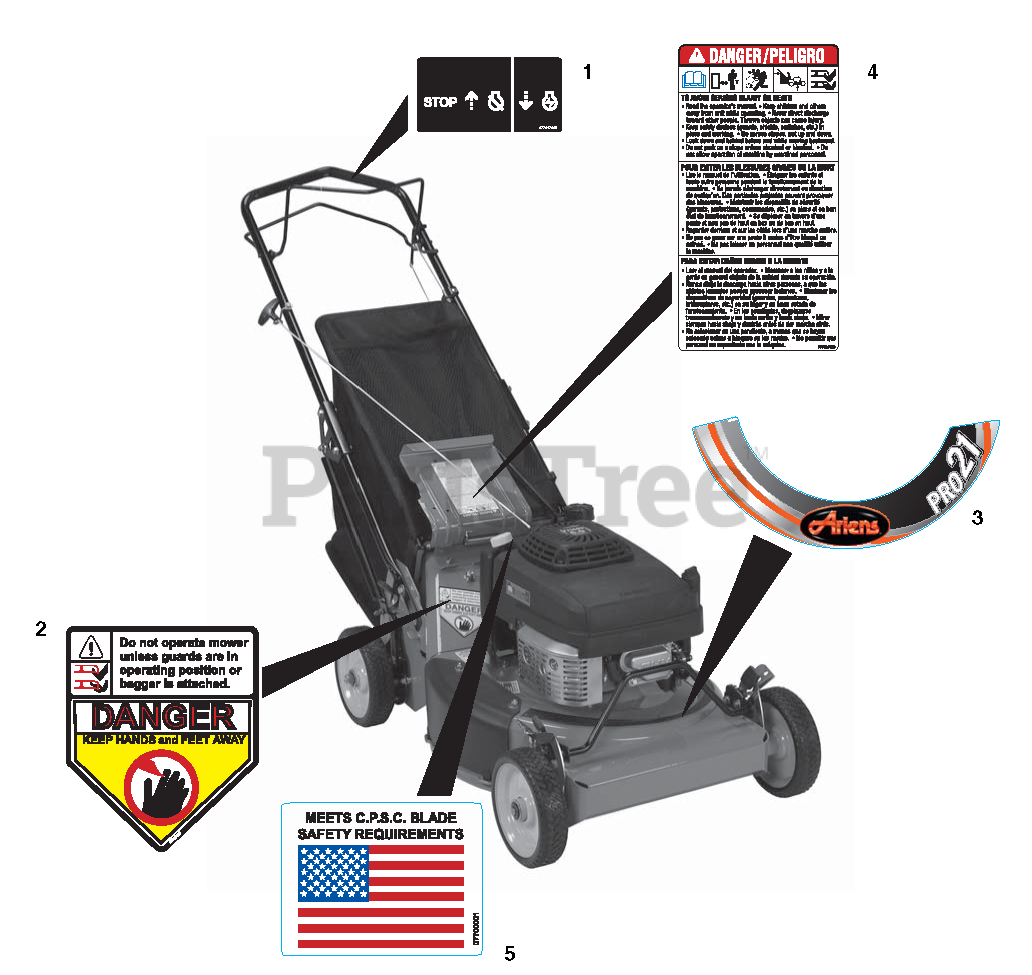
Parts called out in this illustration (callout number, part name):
1	DECAL - ENGINE CONTROL
2	DECAL, CPSC DANGER
3	DECAL, ARIENS PRO21 DECK
4	DECAL, BILINGUAL DANGER
5	DECAL, CPSC/USA FLAG
